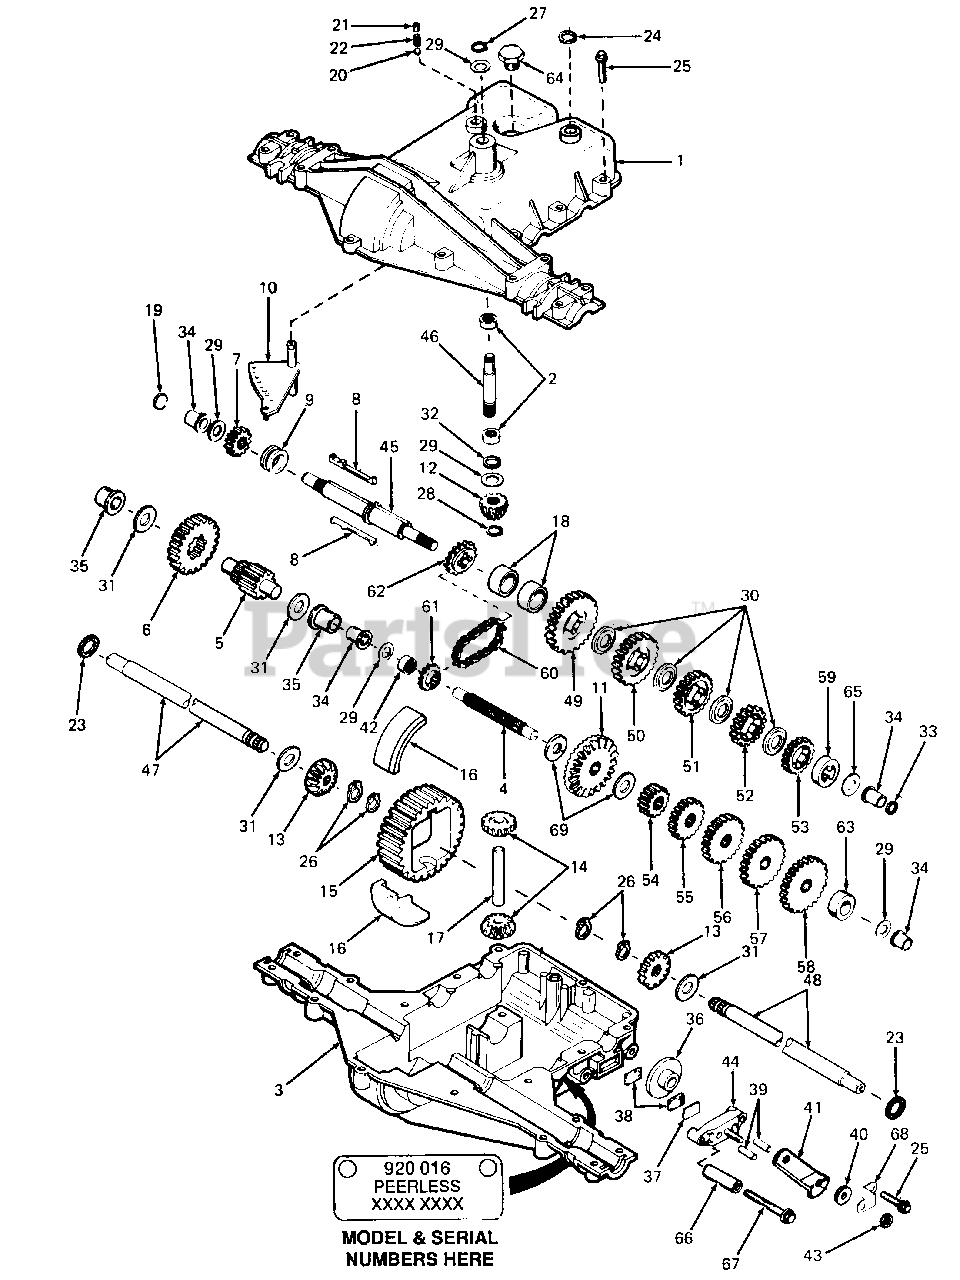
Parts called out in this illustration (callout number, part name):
1	Cover, Transaxle
2	Bearing, Needle
3	Case, Transaxle
4	Shaft, Counter
5	Shaft & Pinion Assy, Output
6	Gear, Output
7	Gear, Spur - 1st
9	Collar, Shifter
10	Rod & Fork Assy, Shift
11	Gear, Bevel (42 Teeth)
12	Gear, Bevel Input
13	Gear, Bevel
14	Gear
15	Gear, Ring
16	Block, Bearing
17	Pin, Drive
18	Spacer, Neutral
19	Disk
20	Ball, 5/16 Dia, Grade 200
23	Ring, Seal
24	Seal, Square Cut
25	Screw, Flanged Hex, 1/4-20 X 1.25 Lg
26	Ring, Retainer (Set of 2)
27	Ring, Retaining
28	Ring, Ext Ret, .521
29	Washer, Thrust
32	Ring, Quad
33	Ring, Sq Cut
34	Bushing, Flanged
36	Brake, Disc
37	Plate, Brake Pad
38	Pad
39	Pin, Dowel
40	Washer, Flat, .344 X 1.0 X.063 HDN
41	Lever, Brake
43	Nut
44	Holder, Brake Pad
45	Shaft, Brake
46	Shaft, Input
47	Axle, 11.62 Lg
48	Axle, 16.0 Lg
49	Gear, Spur (37 Teeth)
50	Gear, Spur (30 Teeth)
51	Gear, Spur (25 Teeth)
52	Gear, Spur (22 Teeth)
53	Gear, Spur (20 Teeth)
54	Gear, Spur (12 Teeth)
55	Gear, Spur (20 Teeth)
56	Gear, Spur (25 Teeth)
57	Gear, Spur (28 Teeth)
58	Gear, Spur (30 Teeth)
60	Chain, Roller
61	Sprocket (9 Teeth)
62	Sprocket (18 Teeth)
65	Washer, Thrust
67	Screw, Hex Flanged Hd, 1/4-20 X 2-1/4 Lg
68	Bracket, Brake Lever
69	Washer, Thrust
